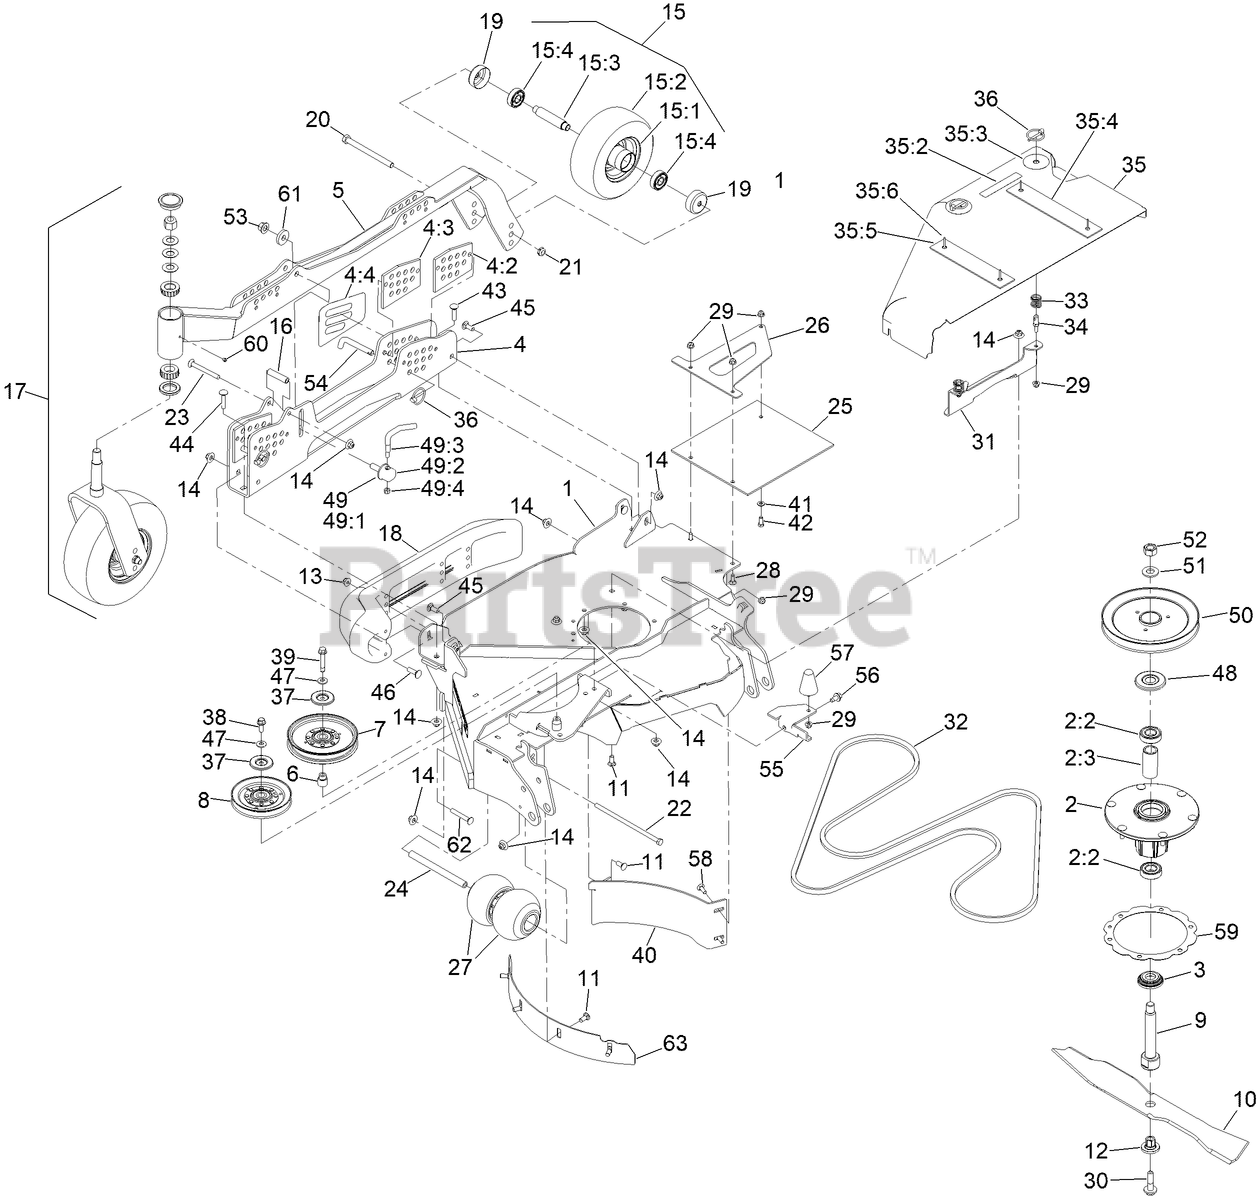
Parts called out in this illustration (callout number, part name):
1	RH WING DECK ASM
2	SPINDLE ASM
2:2	BEARING-BALL
2:3	SPACER-BEARING
3	GUARD-BOTTOM
4	RH HOC CHANNEL ASM
4:2	PLATE-GUIDE, HOC (LH)
4:3	PLATE-GUIDE, HOC (RH)
4:4	DECAL-HEIGHT OF CUT, RH
5	TUBE-HOC , RH
6	BUSHING-IDLER
7	IDLER-PULLEY
8	IDLER-V
9	SHAFT-SPINDLE
10	BLADE-24.50 MULCH
11	BOLT-CARR
12	BUSHING-HEX
13	NUT-HF, NI
14	NUT-FLANGE, NI
15	WHEEL AND TIRE ASM
15:1	WHEEL
15:3	AXLE-CASTER
15:4	BEARING
16	SPACER
17	CASTER WHEEL ASM
18	SKID-BUMPER, DECK
19	GUARD, SEAL
20	SCREW-HH
21	NUT-HEX
22	SCREW-HH
23	SCREW-CARR
24	SPACER-WHEEL
25	GUARD-TIRE
26	SUPPORT-FLAP, RH
27	ROLLER-SCALP, ANTI
28	SCREW-CARR
29	NUT-HF, NI
30	SCREW-SEMS
31	BRACKET-SHIELD MOUNT, OUTER
32	BELT-V
33	SPRING
34	PIN, SPRING
35	RH WING SHIELD ASM
35:2	DECAL-NO STEP
35:3	DECAL-SCRATCH COVER
35:5	PLATE-FRONT
35:6	RIVET-POP
36	PIN-LYNCH
37	SHIELD-DUST
38	SCREW-HHF
39	SCREW-HHF W/ PATCH
40	BAFFLE-BLOCK, RH WING
41	WASHER-PLAIN
42	SCREW-HH
43	SCREW-CARR
44	SCREW-CARR
45	BOLT-CARR
46	BOLT-CARR
47	WASHER-BELLEVILLE
48	GUARD-BEARING, TOP
49	LEVER ASM
49:1	SCREW-LOCK
49:2	CAP-LOCK
49:4	NUT-LOCK, NI
50	SHEAVE-DRIVE, BLADE
51	WASHER
52	NUT-HEX
53	NUT-LOCK
54	PIN-HOC
55	BRACKET-COVER RETAINER
56	SCREW-HWH
57	BUMPER-RUBBER
58	SCREW-CARR
59	RING-SPACER, HOUSING
61	WASHER
62	SCREW-CARR
63	BAFFLE-DEPTH, RH
